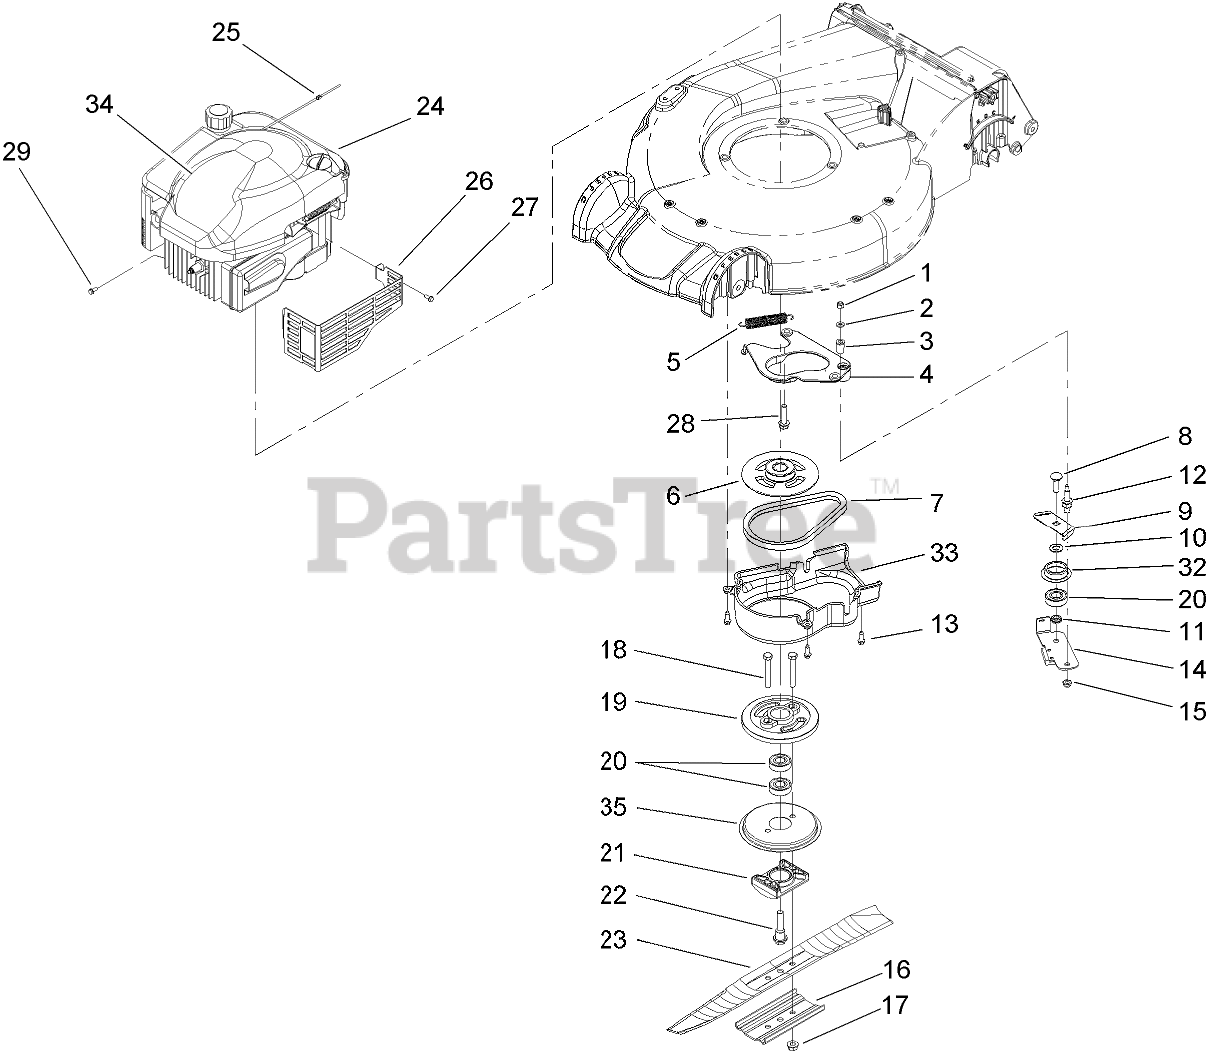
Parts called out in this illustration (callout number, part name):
1	NUT-LOCK, NI
2	WASHER-FLAT
3	BUSHING
4	PLATE-ANCHOR
5	SPRING-TENSION, BRAKE
6	PULLEY
8	BOLT-CARR
9	PLATE-GUIDE
10	WASHER-PLAIN
11	SPACER-BEARING
12	BOLT-SHOULDER
13	SCREW-HWHTF
14	BRAKE ARM ASM
16	SUPPORT-BLADE
17	NUT-LOCK
18	SCREW-HH
19	DRUM
20	BEARING-BALL
21	SUPPORT-BLADE
22	BOLT-CRANK
23	BLADE-RECYCLING
25	STOP-ROPE
26	SHIELD-MUFFLER
27	SCREW-TAPTITE
28	SCREW-HWH
29	SCREW-HWH
32	RETAINER-BELT
34	DECAL-RECOIL
35	DISC
